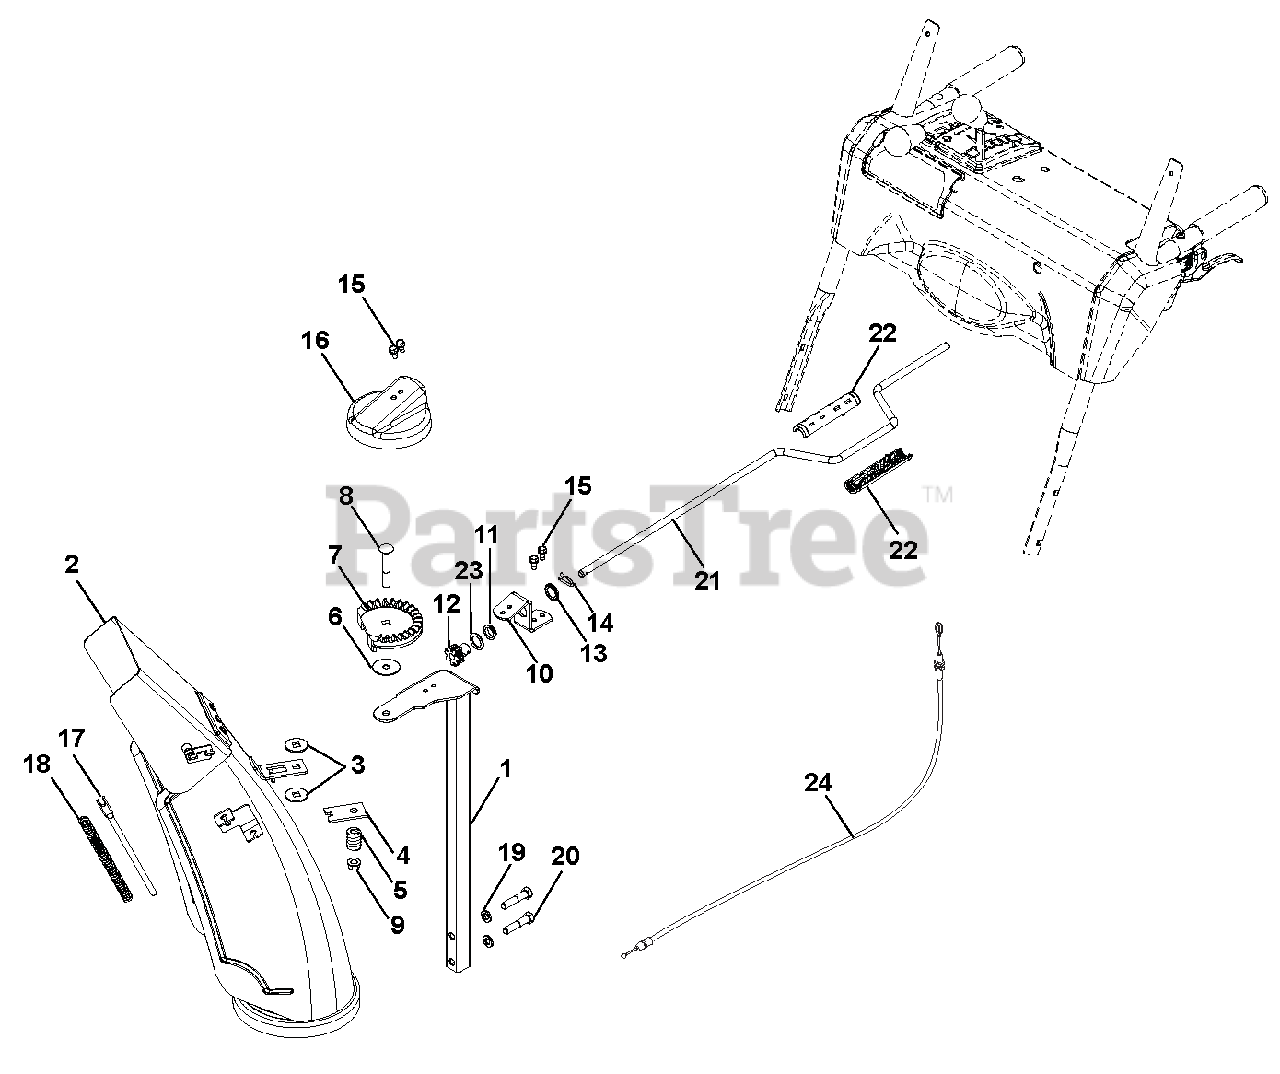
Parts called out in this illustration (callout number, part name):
1	PEDESTAL, CHUTE - CRANK
2	CHUTE, DISCHARGE W/CAP & DECAL
3	FRICTION WASHER
4	PLATE, FRICTION
5	SG-COMP .187X.56X1.62
6	@WSHR-FL-STL .406X1.25X.10 ZC
7	CHUTE GEAR
8	@BLT-RDHDSQNK .38-16X2.50 G5YZ
9	@NUT-LK-TOP-FLG .38-16 YWZC
10	BRACKET, PINION GEAR
11	BUSHING, POLYLINER-.63 SNAPIN
12	PINION GEAR W/BRACKET
13	PUSHNUT .625
14	PIN, SPRING CLIP
15	SCR-TAP .25-20X.50 HWH TR YWZ
16	GEAR COVER
17	ROD, DEFLECTOR CAP
18	SG-COMP .08X.40X6.50 14#/IN
19	@WSHR-LK .38X.094 REG YWZC
20	@BLT-HEX .38-16X1.75 GR5 YWZC
21	ROD, CHUTE CRANK
22	KNOB, CRANK-SNAP
23	WSHR-THRST .625 X 1.0 X .03
24	CABLE, DEFLECTOR-COATED
